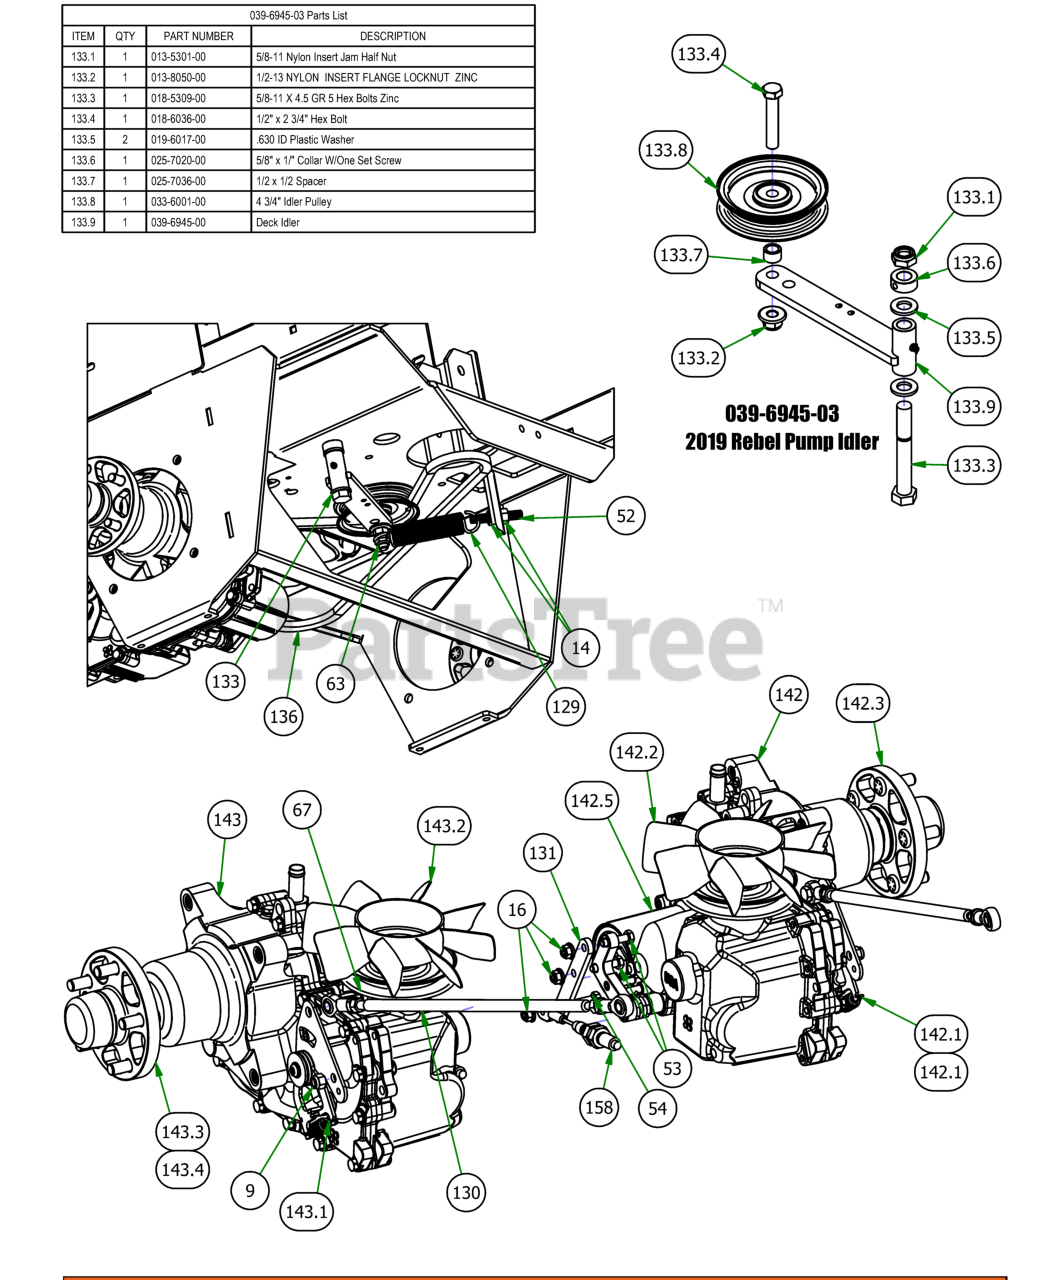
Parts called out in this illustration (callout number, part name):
9	3/8 Nylock Nut
14	1/2" Hex Nut
16	5/16" Nylon Flange Nut
52	All Thread-Pump Idler Tensioner
53	5/16 x 1 1/4 Hex Bolt
54	5/16" x 1" Bolt
63	1/2" Nylcock Nut (1/2 Jam)
67	3/8" x 1 1/4" Hex Bolt
129	Deck spring big diameter
130	2019 Rebel Push Rod Assembly
131	2015 Outlaw Brake Adapter (4400 Transaxles Only)
133	2019 Rebel Pump Idler
133.1	5/8-11 Nylon Insert Jam Half Nut
133.2	1/2-13 NYLON INSERT FLANGE LOCKNUT ZINC
133.3	5/8-11 X 4.5 GR 5 Hex Bolts Zinc
133.4	1/2" x 2 3/4" Hex Bolt
133.5	.630 ID Plastic Washer
133.6	5/8" x 1/" Collar W/One Set Screw
133.7	1/2 x 1/2 Spacer
133.8	4 3/4" Idler Pulley
133.9	Deck Idler
136	2019 Rebel Pump Belt
142	4400 Transaxle-Left-Base Outlaw/2019 Rebel
142.1	Gold Transaxle Spring
142.2	Fan/Pulley Kit for 4400 Outlaw
142.3	Hub for 4400 Transaxle
142.5	Hydro Filter for 4400 Transaxle
143	4400 Transaxle-Right-Base Outlaw/2019 Rebel
143.1	Gold Transaxle Spring
143.2	Fan/Pulley Kit for 4400 Outlaw
143.3	Hub for 4400 Transaxle
143.4	Seal Kit for 4400 Series Outlaw Transaxle
158	Long Brake Cable
